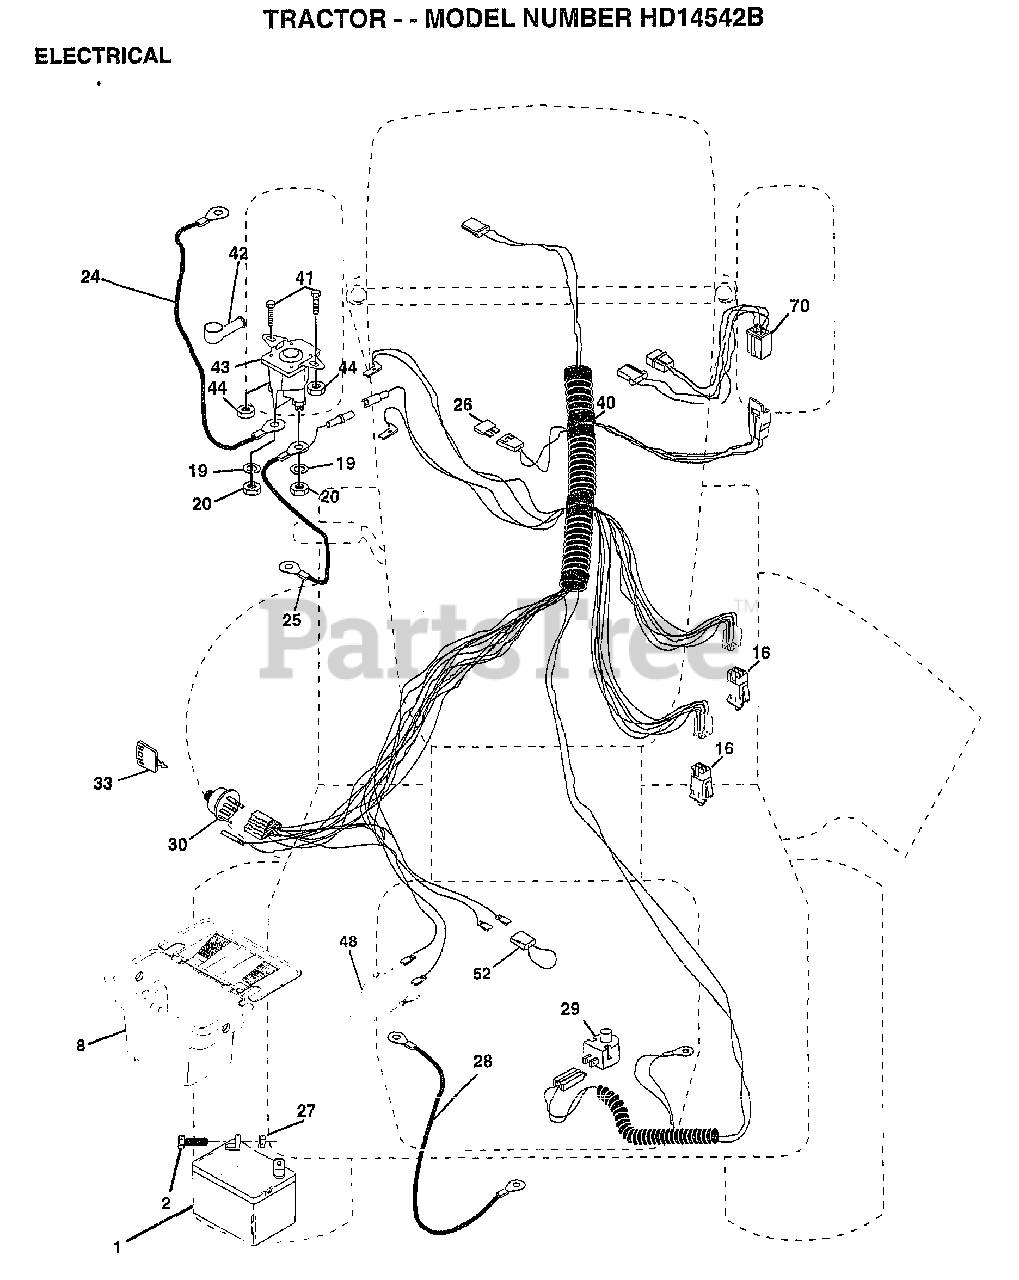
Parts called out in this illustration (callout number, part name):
2	BOLT LT
8	"CASE,BATTERY.MECH"
16	SWITCH INTERLOCK
20	NUT
21	HARNESS.ASM.LIGHT W/4152J
22	HEADLAMP BULB
24	"CABLE T, BATTERY"
25	CABLE.BTRY.6GA.RD
26	FUSE.15 AMP
27	NUT
28	CABLE T
29	SWITCH SEAT
30	SWITCH IGN 4POS
31	NUT IGNITION
32	COVER KEY SWITCH
33	KEY
40	HARNESS.IGNITION
41	BOLT HXHD FIN
44	NUT HXKEP 1/4X20
48	ADAPTER AMMETER
52	PROTECTION LOOP
70	HARNESS.ENGINE.B&S
